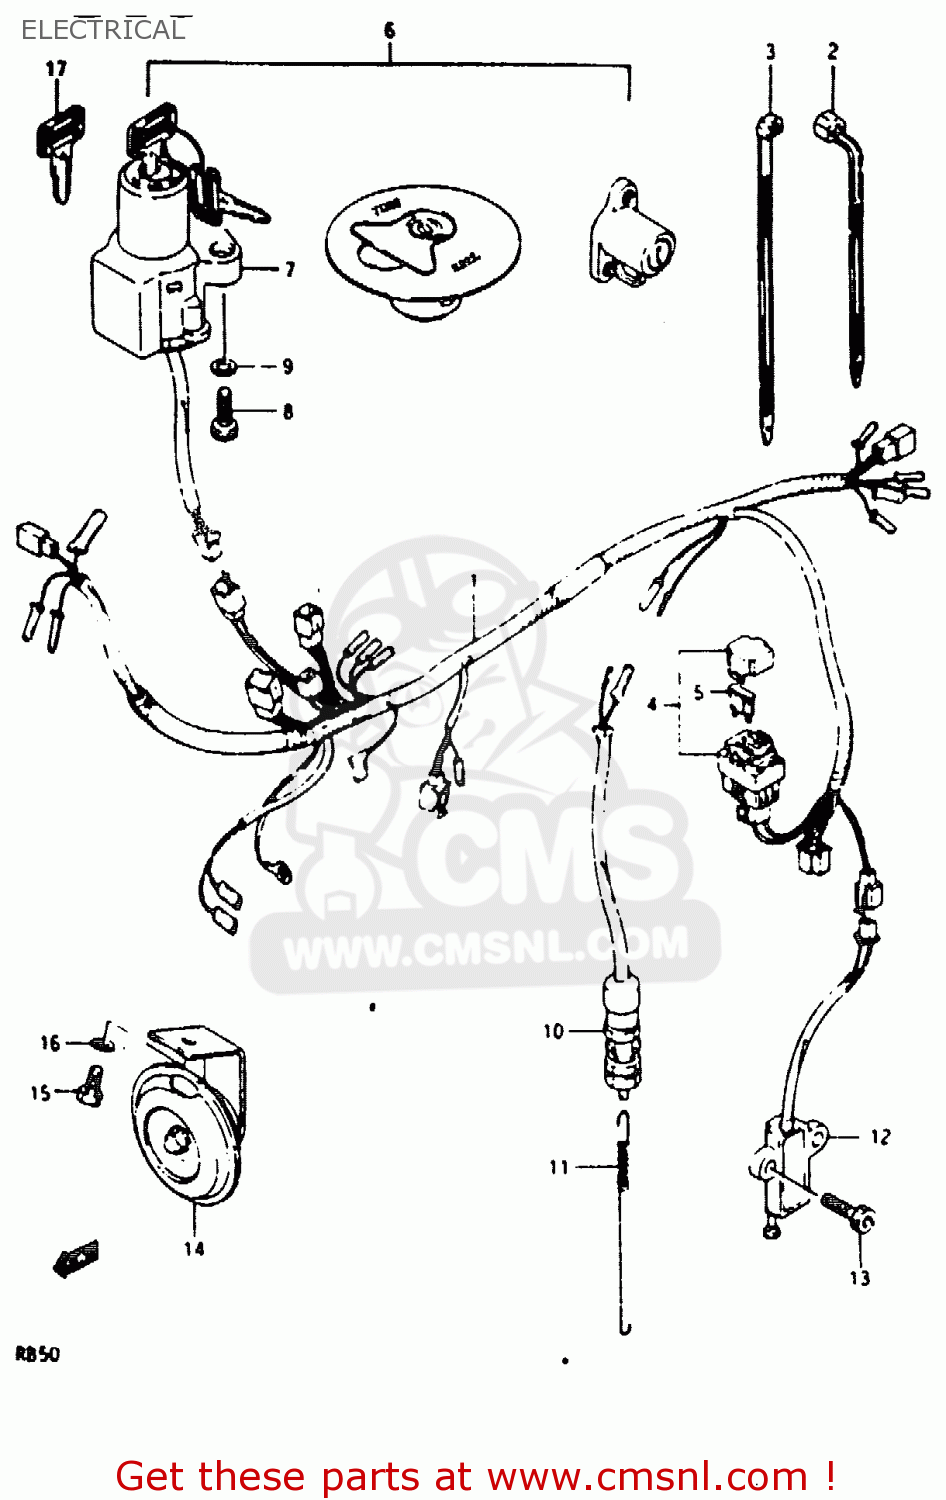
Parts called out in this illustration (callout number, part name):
1	HARNESS,WIRING
2	CLAMP(L:95)
3	CLAMP
4	BOX ASSY,FUSE
5	FUSE(15A)
6	LOCK SET
7	LOCK ASSEMBLY,STEERING
8	BOLT
9	WASHER,LOCK
10	SWITCH ASSY,STOP LAMP
11	SPRING
13	BOLT, 6X16
15	BOLT
16	WASHER, LOWER
17	KEY,BLANK
